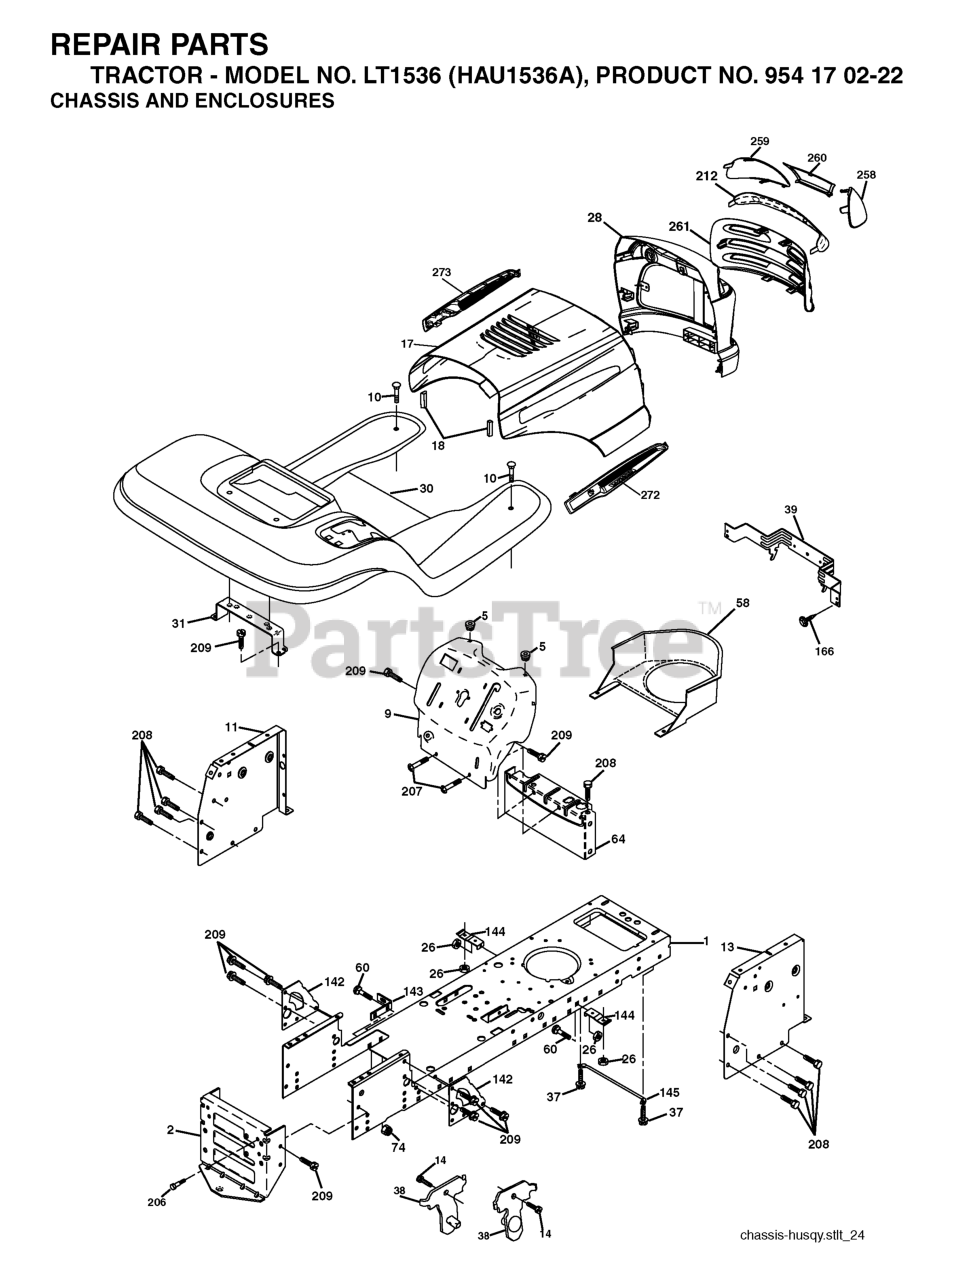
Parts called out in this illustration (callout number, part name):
1	CHASSIS STAMPING
2	DRAWBAR, 12GA
5	BUMPER.RUBBER.HOOD
9	DASH
10	BOLT D
11	PANEL.DASH.LH.LTX
13	PANEL DASH RH
17	VENT.HOOD.LASER.III
18	BUMPER.HOOD.LARGE.1.75"
26	NUT
30	FENDER FOOTREST
31	BRACKET.SUPPORT.FENDER
37	Screw 5/16-18 x 1/2 Hex, Self Tapping 5/16-18 x 1/2
38	BRACKET.ASM.PIVOT.MOWER.REAR
39	BRACKET PIVOT LASER
60	Bolt - Rd. Hd. Sq. Neckiage 3/8 16 x 3/4
64	DASH LOWER
142	PLATE REINFORCEMENT
143	BRACKET, SWAYBAR CHASSIS
144	BRKT, FOOT REST
145	ROD PIVOT CHASSIS/HOOD
166	SCREW
206	SHOULDER BOLT 5/16-18TT
207	SCREW, 5/16-18 X 1/2
208	SCREW 3/8-16X1/2
209	SCREW, 3/8-16X3/4
212	INSERT.LENS.REFLECTIVE
258	LENS LH
259	LENS LH
260	COVER.LENS.HUSQ.LASER
272	VENT.HOOD.LASER.
273	VENT.HOOD.LASER.
